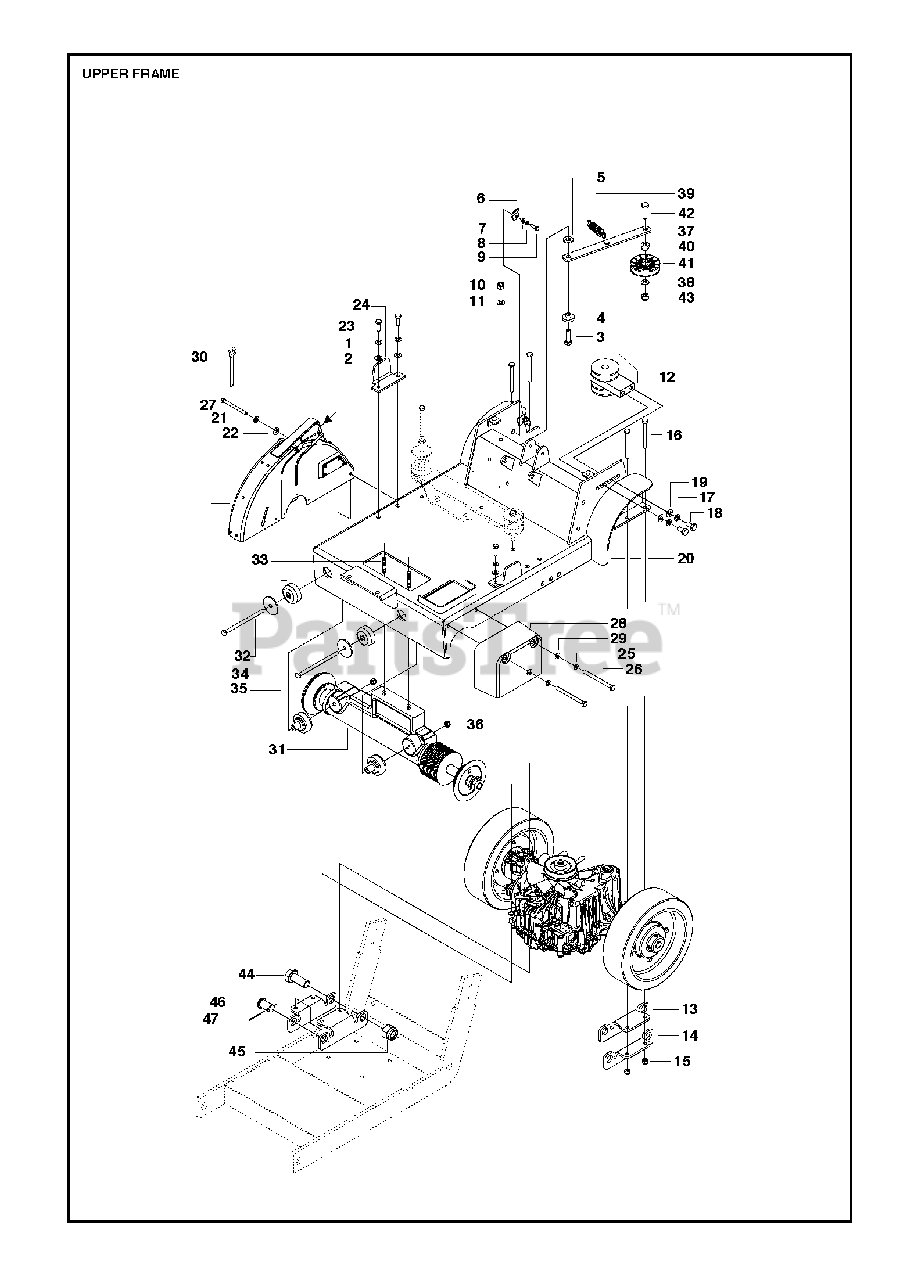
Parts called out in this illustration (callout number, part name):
1	SPRING WASHER
2	WASHER
10	HEXAGON LOCKING NUT
11	WASHER
15	HEXAGON LOCKING NUT
19	WASHER
21	SPRING WASHER
22	WASHER
25	SPRING WASHER
29	WASHER
32	HHCS. M10X1.5X130MM Z/P
36	HEXAGON LOCKING NUT
38	WASHER
43	HEXAGON LOCKING NUT
